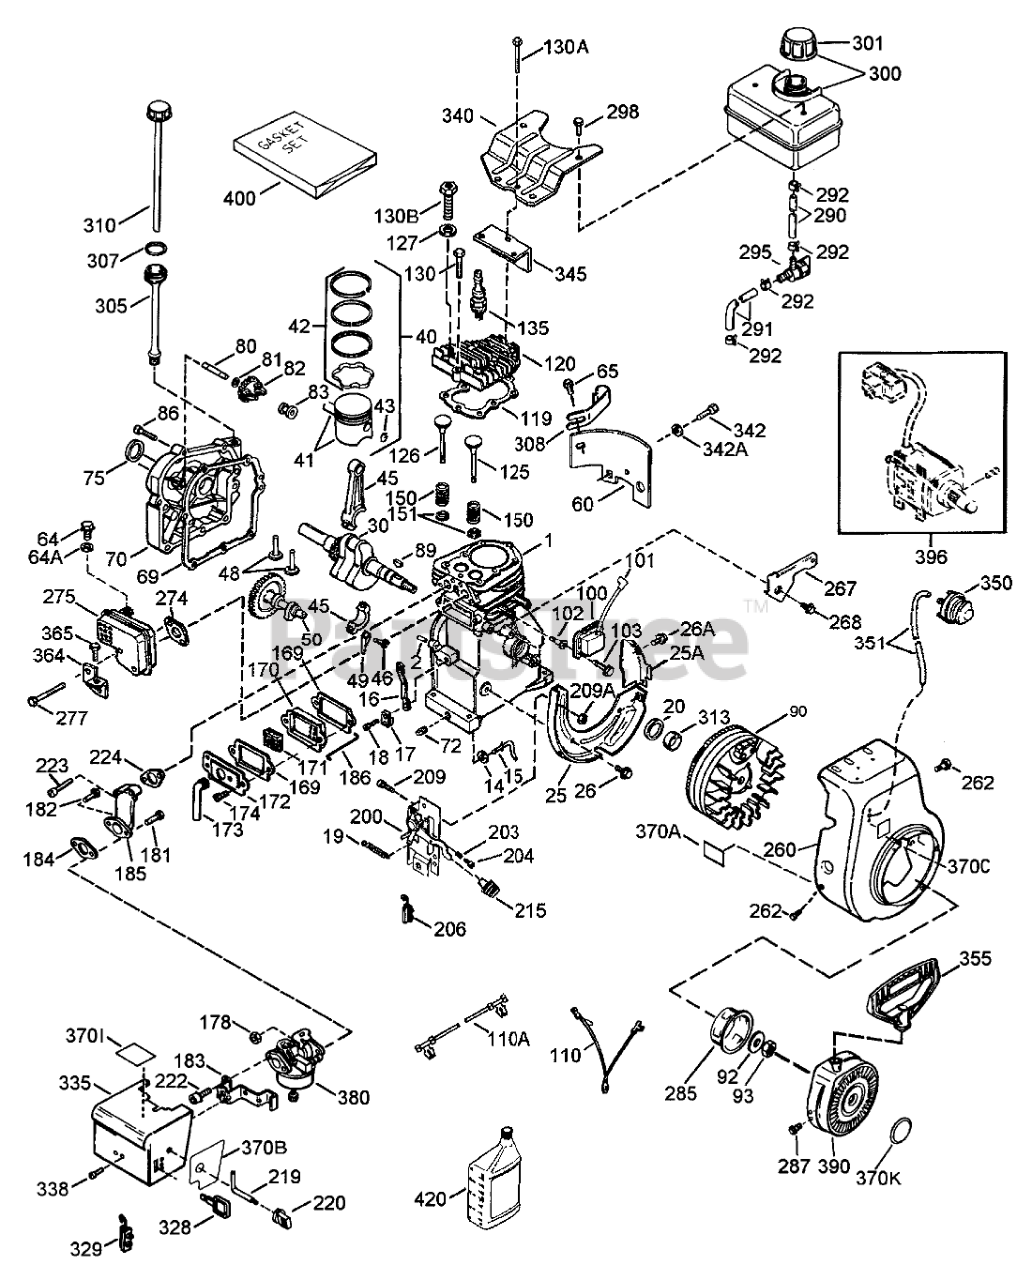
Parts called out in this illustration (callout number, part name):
1	Cylinder Assembly (Incl. Ref. #2, 20, 72 &
2	Pin-Dowel
14	Washer-Flat
15	Rod-Governor
16	Lever-Governor
17	Clamp-Lever, Governor
18	Screw (T-15, 8-32 x 19/64)
19	Spring-Extension
20	Seal-Oil
25	Baffle-Housing, Blower
25A	Extension-Baffle
26	Screw (1/2-20x5/8)
26A	Screw (8-32 x 21/64)
30	Crankshaft ASM
40	Set-Piston, Pin & Ring (Std)
41	Piston & Pin Asm.. Standard (Incl. Ref. #43)
42	Ring Set (STD)
43	Ring-Retaining, Piston Pin
45	Connecting Rod Assembly (Incl. Ref. #46 & 49)
46	Bolt-Rod, Connecting
48	Lifter-Valve
49	Dipper-Oil
50	Camshaft
60	Extension-Blower
64	Screw
64A	Washer
65	Screw
69	Gasket-Cover, Cylinder
70	Cover-Cylinder (Incl. Ref. #75 & 80)
72	Plug-Drain, Oil (SQH 1/4-18)
75	Seal-Oil
80	Shaft-Governor
81	Washer-Flat
82	Gear-Governor (Incl. Ref. #81)
83	Spool-Governor
86	Screw (1/4-20 x 1-1/4)
89	Key-Flywheel
90	Flywheel
92	Washer-Belleville
93	Nut-Flywheel
100	Solid State Ignition (Incl. 101)
101	Cover-Spark Plug
102	Stud-Mounting, Solid State
103	Screw (T-15, 10-24 x 15/16)
110	Wire-Ground
110A	Wire-Ground (Green, 5.5)
119	Gasket-Head, Cylinder
120	Head-Cylinder (Incl. Ref. #131)
125	Valve-Exhaust Standard (Incl. Ref. #151)
126	Valve-Intake Standard (Incl. Ref. #151)
127	Washer-Flat
130	Screw (5/16-18x1-1/2)
130A	Screw (5/16-18 X 2)
130B	Screw ( 5/16-18 x 1-1/2)
135	Spark Plug-Resistor (R J19 L M)
150	Spring-Valve
151	Cap-Valve, Spring
169	Gasket-Cover, Valve
170	Body-Breather
171	Element-Breather
172	Cover-Breather
173	Tube-Breather
174	Screw (10-24 x 3/4)
178	Nut and Lock Washer (1/4-28)
181	Screw (1/4-28 x 1-11/16)
182	Screw (1/4-28 x 7/8)
183	Bracket-Choke
184	Gasket
185	Pipe-Intake
186	Link-Governor to Throttle
200	Control Assembly (Incl. Ref.# 203, 204, 206, 209 & 209A)
203	Spring-Compression
204	Screw (T-10, 5-40x7/16)
206	Terminal
209	Screw
209A	Nut-Lock
215	Knob-Control
219	Rod-Choke
220	Knob-Control
222	Screw (10-32 x 1/2)
223	Screw (1/4-20 x 1-19/32)
224	Gasket-Intake
260	Housing-Blower
262	Screw (1/4-20 x 1/2)
267	Bracket-Hold Down
268	Screw (10-24 x 9/16)
274	Gasket-Exhaust
275	Muffler (Incl. Ref.# 274)
277	Screw-Fil. Hd.
285	Cup-Starter
287	Screw (8-32 x 21/64)
290	Line-Fuel
291	Line-Fuel (8.62)
292	Clamp-Line, Fuel
295	Valve-Shut Off, Fuel
298	Screw (1/4-15x7/8)
300	Tank Assembly-Fuel (Incl. Ref. #292 & 301)
301	Cap-Fuel
305	Tube-Fill, Oil
307	O-Ring
308	Clip-Tube, Fill
310	Dipstick
313	Spacer
328	Key-Ignition
329	Terminal
335	Cover-Carburetor
338	Screw (8-32 X 5/16)
340	Plate-Fuel Tank
342	Screw
342A	Washer
345	Baffle-Heat
350	Primer ASM
351	Line-Primer
355	Handle-Starter, Mitten Grip
364	Bracket-Cover, Carburetor
365	Screw (10-24 x 3/8)
370A	Decal-Lubrication
370B	Decal-Control
370C	Decal-Primer, International Symbol
370I	Decal-Warning (Bilingual)
370K	Decal-Tecumseh Logo for Top of Recoil Starter
380	Carburetor (Incl. Ref. #184)
390	Starter-Rewind
396	Starter-Electric (110 Volt)
400	Gasket Set (Incl. Parts Marked )(26756 (1), 27234A (2), 27272A (1), 27677A (1) 29673 (1), 36443 (1), 33670A (1), 33673A (1)
420	Oil-Engine (SAE 5W30)
